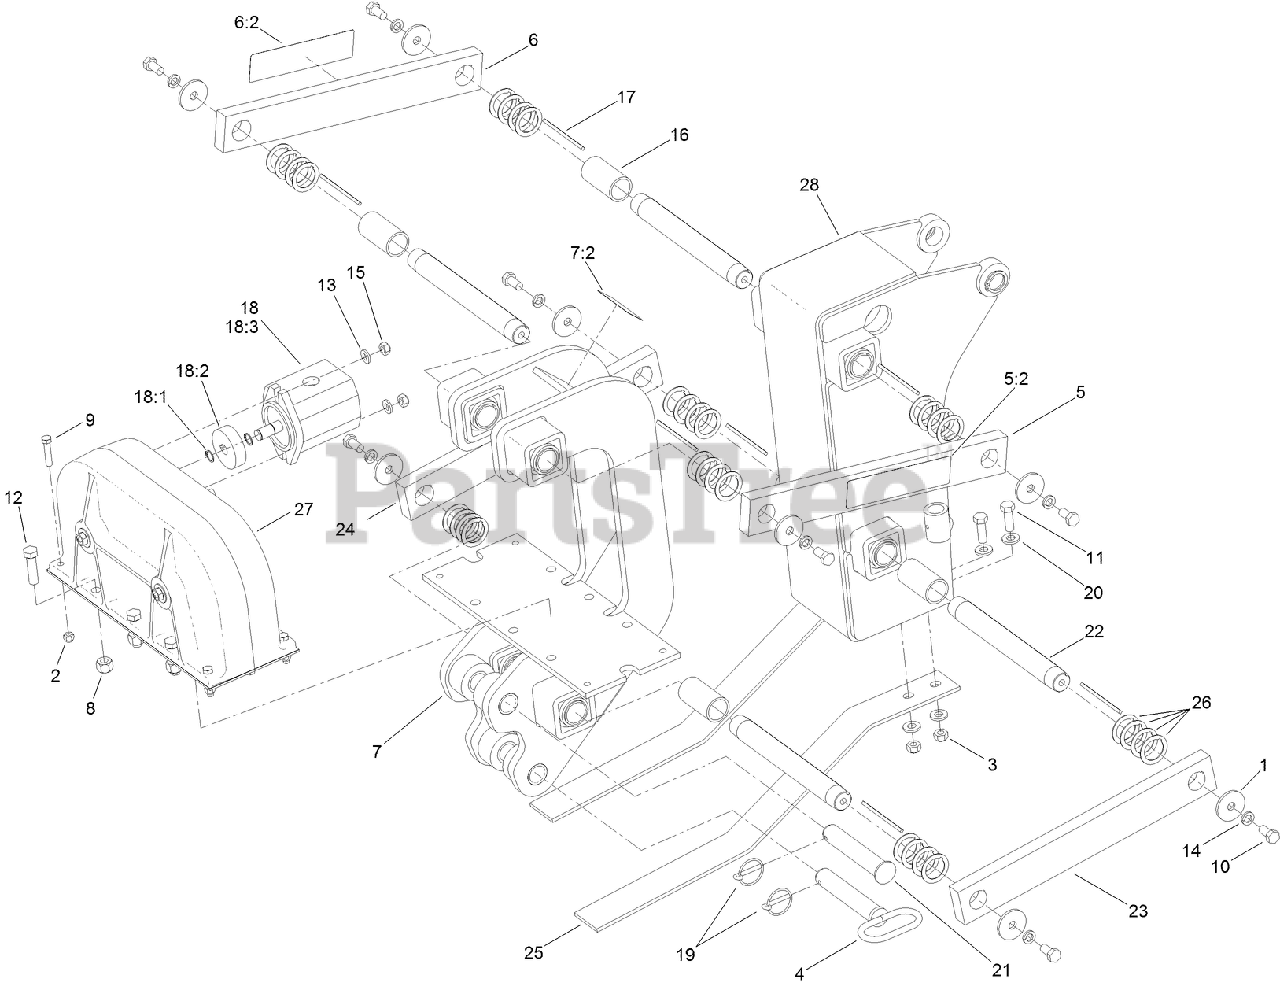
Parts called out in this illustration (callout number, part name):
1	WASHER-THRUST
2	NUT-HEX
3	LOCKNUT
5	RH UPPER BAR AND DECAL ASM
5:2	DECAL-DANGER, PLOW
6	LH UPPER BAR AND DECAL ASM
6:2	DECAL-DANGER, PLOW
7	MOUNTING BLADE AND DECAL ASM
7:2	DECAL-DANGER
9	SCREW-HH
10	SCREW-HH
11	SCREW-HH
13	WASHER
14	WASHER-LOCK
15	NUT-HEX
16	TUBE-SPACER
17	KEY-SQUARE
18	HYD GEAR MOTOR ASM
18:1	RING-RETAINING
18:2	GEAR-MOUNTING, DRIVE
18:3	GEAR MOTOR ASM
19	PIN-KLIK
21	PIN-MOUNTING, BLADE
22	SHAFT-MOUNTING, PLOW ARM
23	ARM-PLOW, LOWER (RH)
24	ARM-PLOW, LOWER (LH)
25	SPRING-SHOE
26	SHIM-ARM
27	GEAR CASE ASM
28	FRAME-LIFT, PLOW
